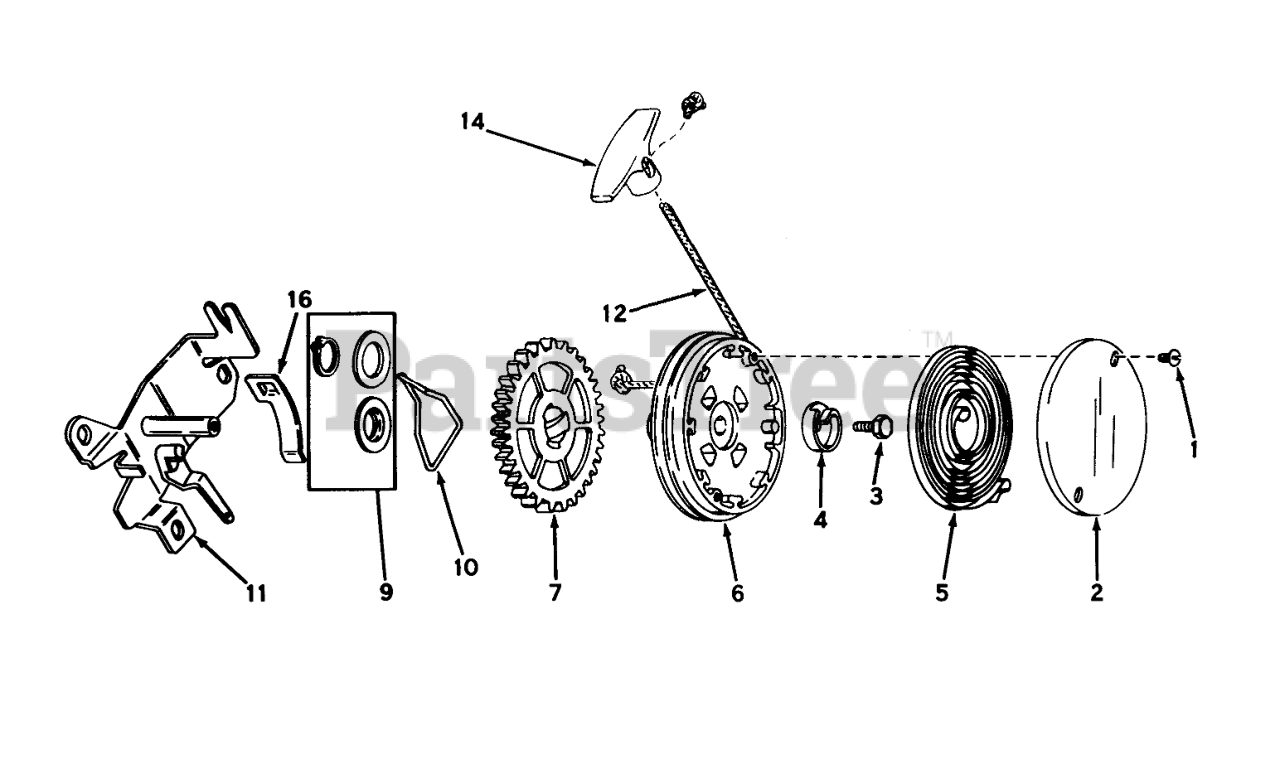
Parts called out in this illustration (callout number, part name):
2	Cover, Spring
3	Screw, Hex Washer Head
4	Hub Spring
5	Spring, Rewind
6	Pulley Assembly (Incl. No.9)
9	Kit, Thrust Wash. & Snap Rg.
11	Bracket Assy., Mounting
12	Rope-Starter
14	Handle-Starter
16	Clip Rope
